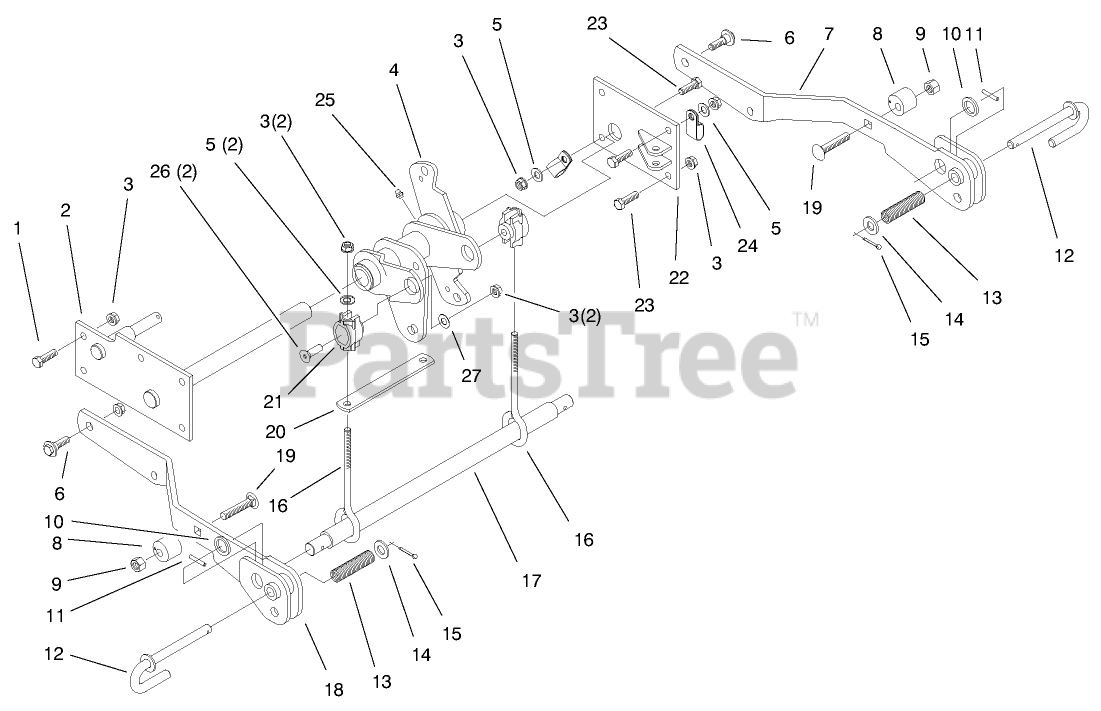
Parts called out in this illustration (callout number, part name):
1	SCREW-HH
2	SUPPORT-LIFT, DECK
3	NUT-LOCK, NI
4	BELLCRANK AND BUSHING ASM
5	WASHER-FLAT
6	SCREW-SHOULDER, HWH
7	ARM-LIFT, LH
8	STOP-LIFT, ADJ.
9	NUT-LOCK, NI
10	WASHER-FLAT
11	PIN-ROLL
12	PIN - J
13	SPRING-COMPRESSION
14	WASHER-FLAT
15	PIN-COTTER
17	BAR-LIFT
18	ARM-LIFT, RH
19	SCREW-CARR
21	SLEEVE-LIFT
22	SUPPORT-CYLINDER
23	SCREW-HH
24	CLAMP-TUBE
25	FITTING-GREASE
26	SCREW-HSFH
27	WASHER-FLAT
